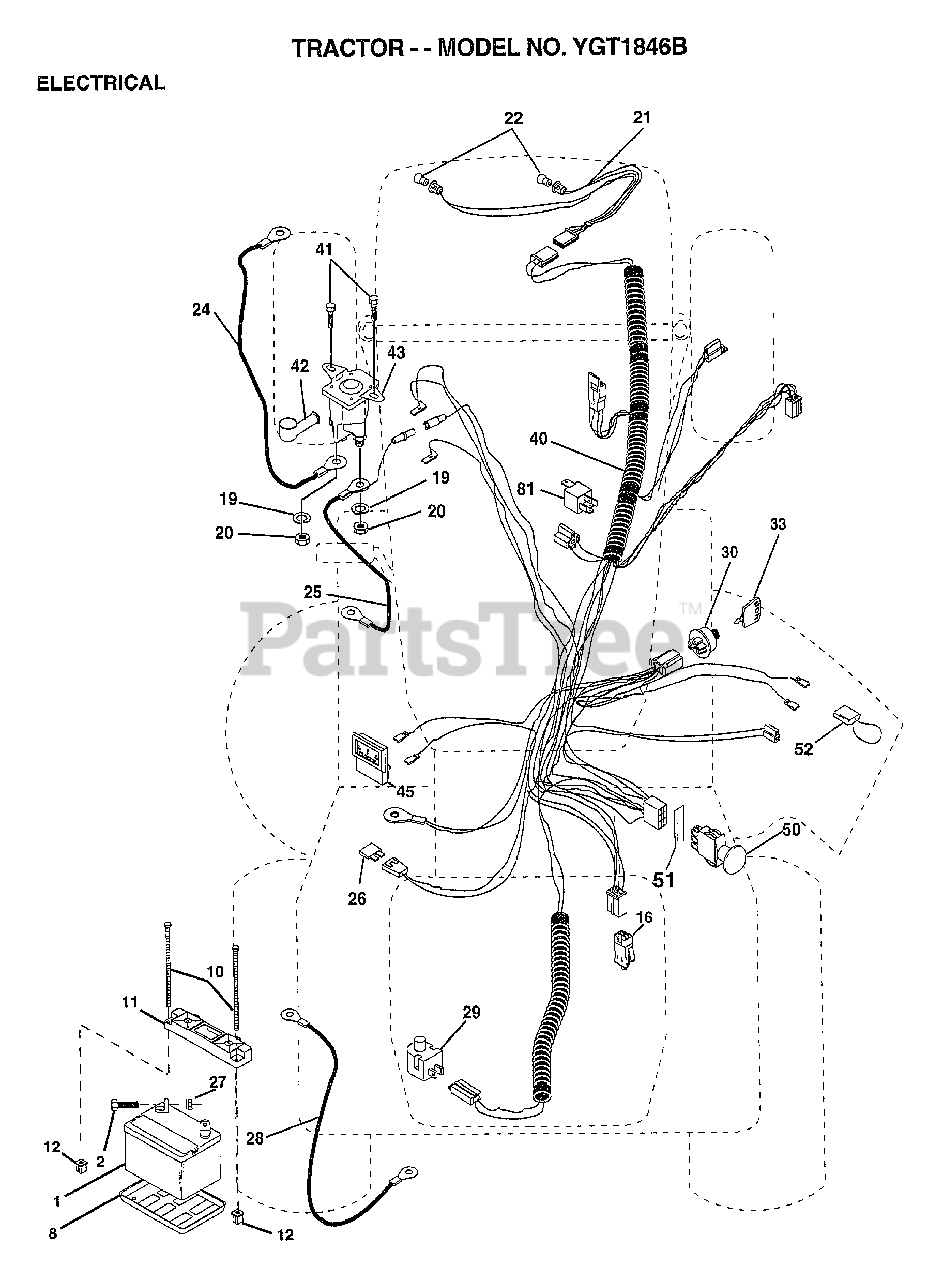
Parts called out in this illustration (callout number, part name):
2	BOLT LT
8	"TRAY T, BATTERY"
11	HOLDDOWN BATTERY
16	SWITCH INTERLOCK
20	NUT
21	HARNESS.ASM.LIGHT.W/4152J
22	HEADLAMP BULB
24	CABLE.BATY.22.RED
25	CABLE.BATRY.4GA.
26	FUSE HYT
27	NUT
28	"CABLE BATTERY,GRD"
29	SWITCH.PLUNGER
30	SWITCH.IGN.
33	KEY MLD GEN DELTA
40	HARNESS.IGN.
41	SCREW
45	AMMETER
50	PTO SWITCH.BLK
51	RING RETAIN PTO
52	PROTECTION LOOP
81	RELAY ASSY T
